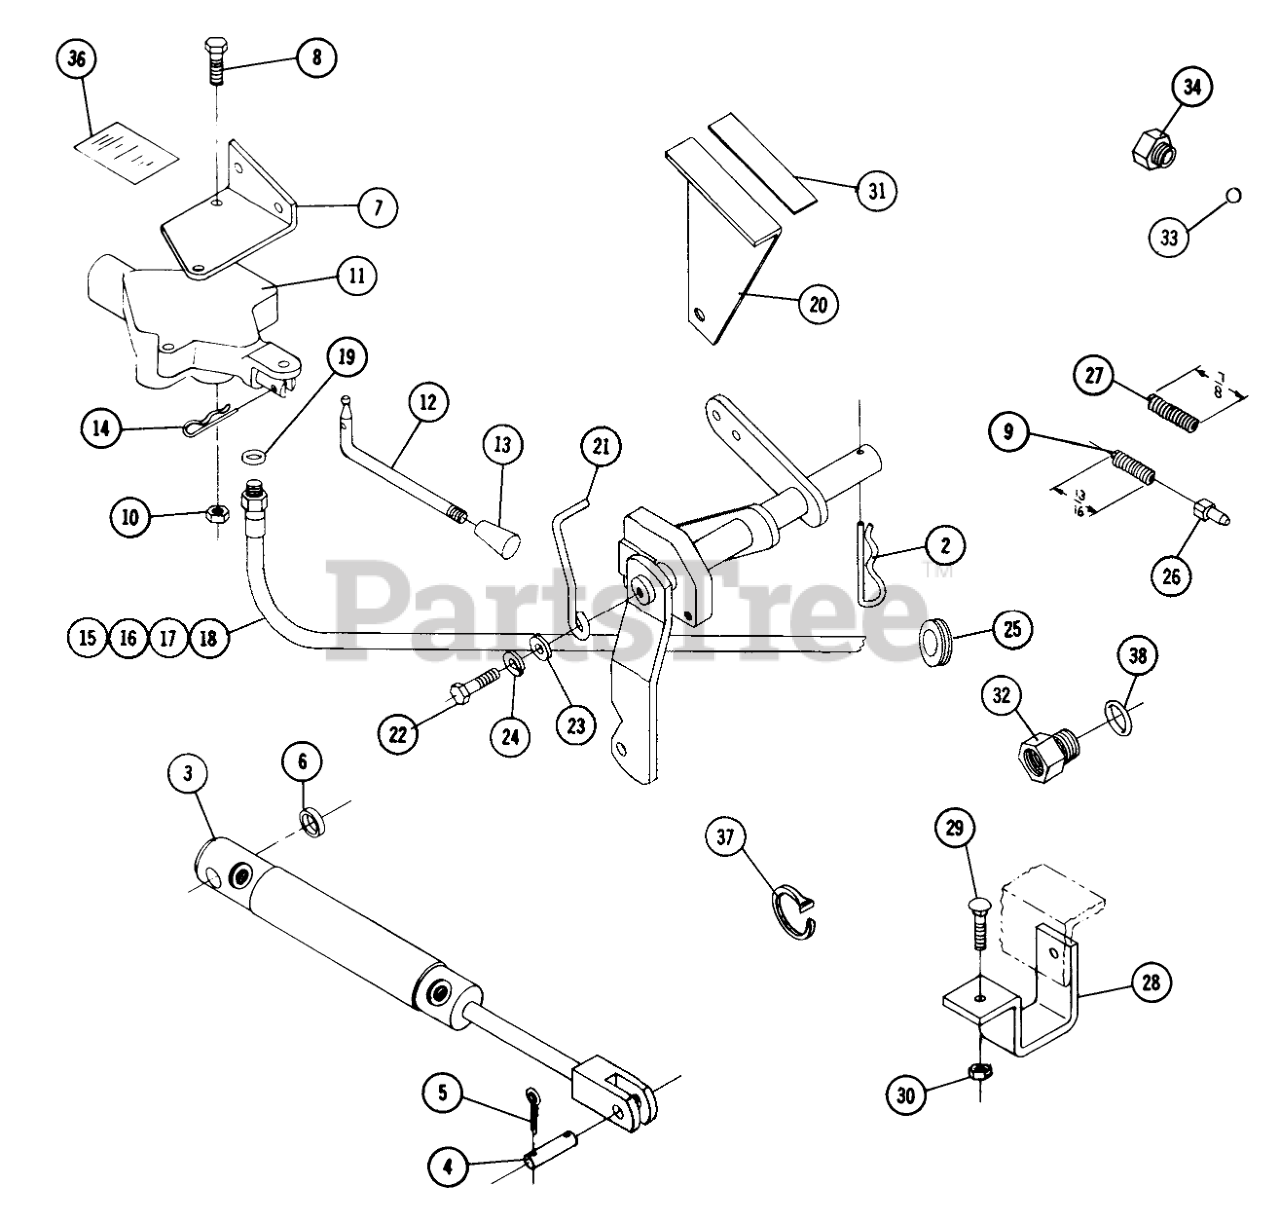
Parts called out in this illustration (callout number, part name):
1	Lift Arm
2	Hairpen
3	Cylinder
4	PIN
5	Cotter Pin
6	Spacer
7	Support Valve
8	Bolt 1/4 20 x 1 1/4
9	SPRING VALVE SUNSTR
10	Nut-Nylok
11	Valve
12	VALVE LEVER
13	Knob
14	Hairpin
15	HYD HOSE ASSY
16	HYD HOSE ASSY
17	Ass-y . Hose-14 1/2
18	HYD HOSE ASSY
19	O RING
20	Indicator Plate
21	Arm
22	Bolt 5/16-18 x
23	Washer
24	Lockwasher
25	Grommet
26	Cone
27	Spring
28	Bracket
29	Bolt-Carriage 5/16-18
30	Nut 5/16-18
31	Decal
32	FITTING REDUCER
33	Ball
35	Bolt, 3/8-16 x 3/4 S.T.
36	Spring
37	PLASTIC TIE
38	0-Ring
39	Shim Set
